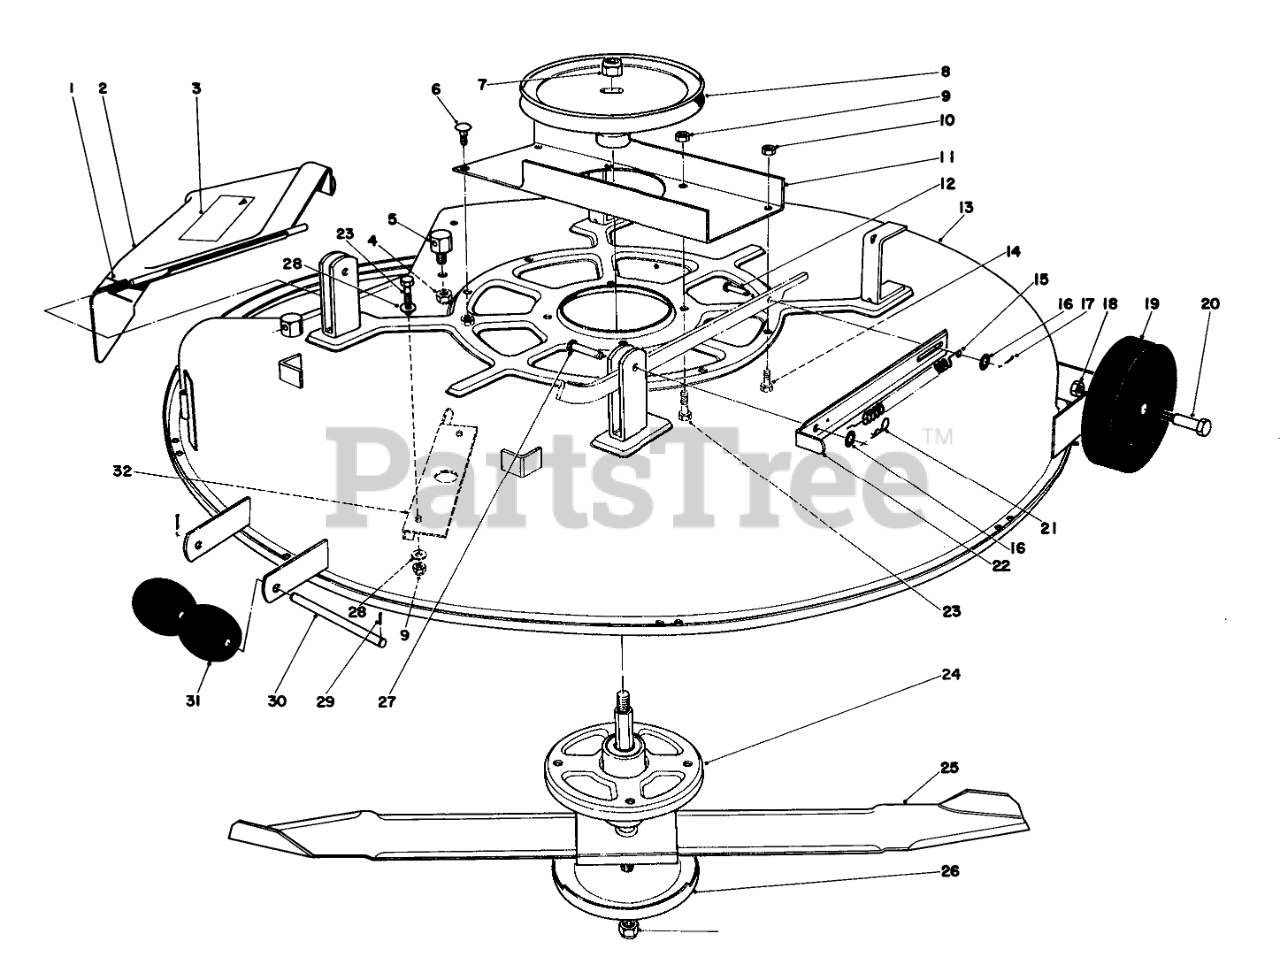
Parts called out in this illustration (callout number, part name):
1	SPRING
2	Deflector Assembly (Incl. Ref. #3)
3	Decal
4	NUT-LOCK, SIDE
5	POST-PIVOT
6	SCREW-CARRIAGE
8	PULLEY(BLADE DRIVE)
9	NUT-LOCK, NI
10	NUT-HEX, SIDE DEFORM
11	REINFORCEMENT CHANNEL
12	PIN-CLEVIS
13	Cutter Deck (Incl. Ref. #9, 23, 28 & 32)
14	SCREW-HH
15	DECK TENSION SPRNG O
16	WASHER-FLAT
17	PIN-COTTER
18	Nut
19	DECK WHEEL
21	PIN-COTTER
22	DECK SPRING STRAP R
23	SCREW-HH
24	Spindle Assembly
25	Blade
26	Axle Support
27	PIN-CLEVIS
28	WASHER-PLAIN
29	PIN-COTTER
30	ROLLER SHAFT
31	ROLLER
32	Baffle Deck
